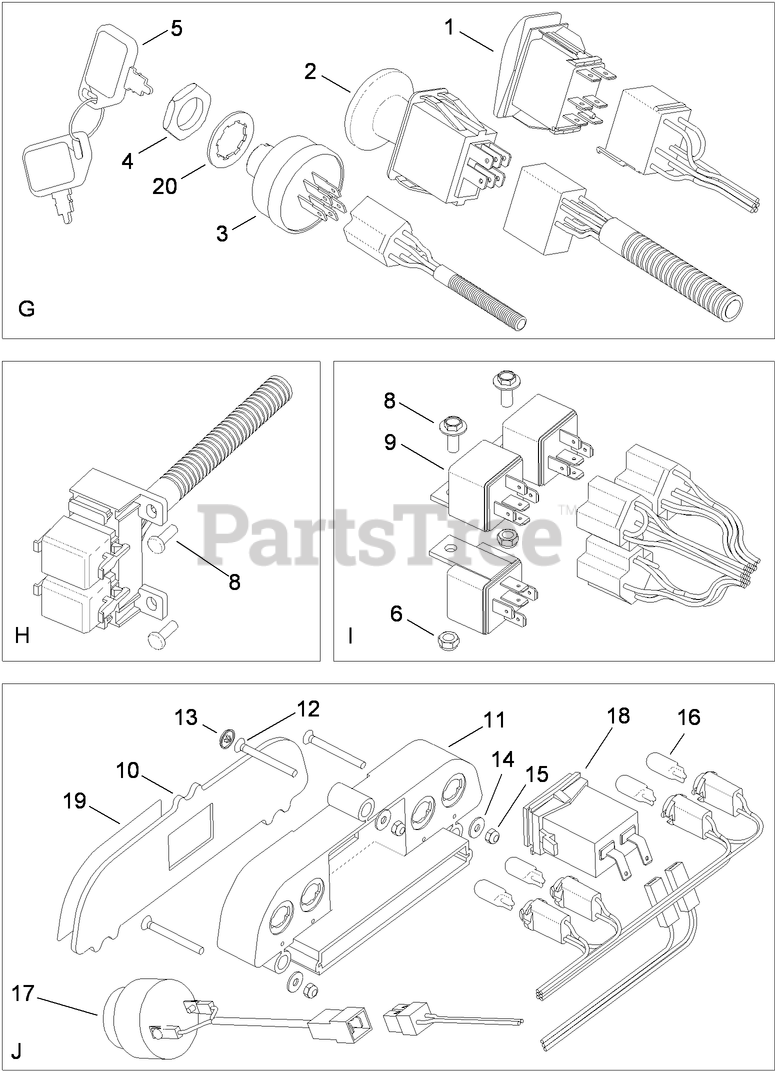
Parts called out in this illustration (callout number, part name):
1	SWITCH-CRUISE
2	SWITCH-PTO,ON-ON-NONE
3	SWITCH-IGNITION
4	NUT-HH
5	KEY-IGNITION
6	NUT-LOCK
8	SCREW-HEX
10	LENS-DASH
11	HOUSING-LIGHT, INDICATOR
13	CAP-SCREW
14	WASHER
15	NUT-HEX
17	BUZZER
18	HOURMETER
19	DECAL-DASH
20	WASHER-LOCK
